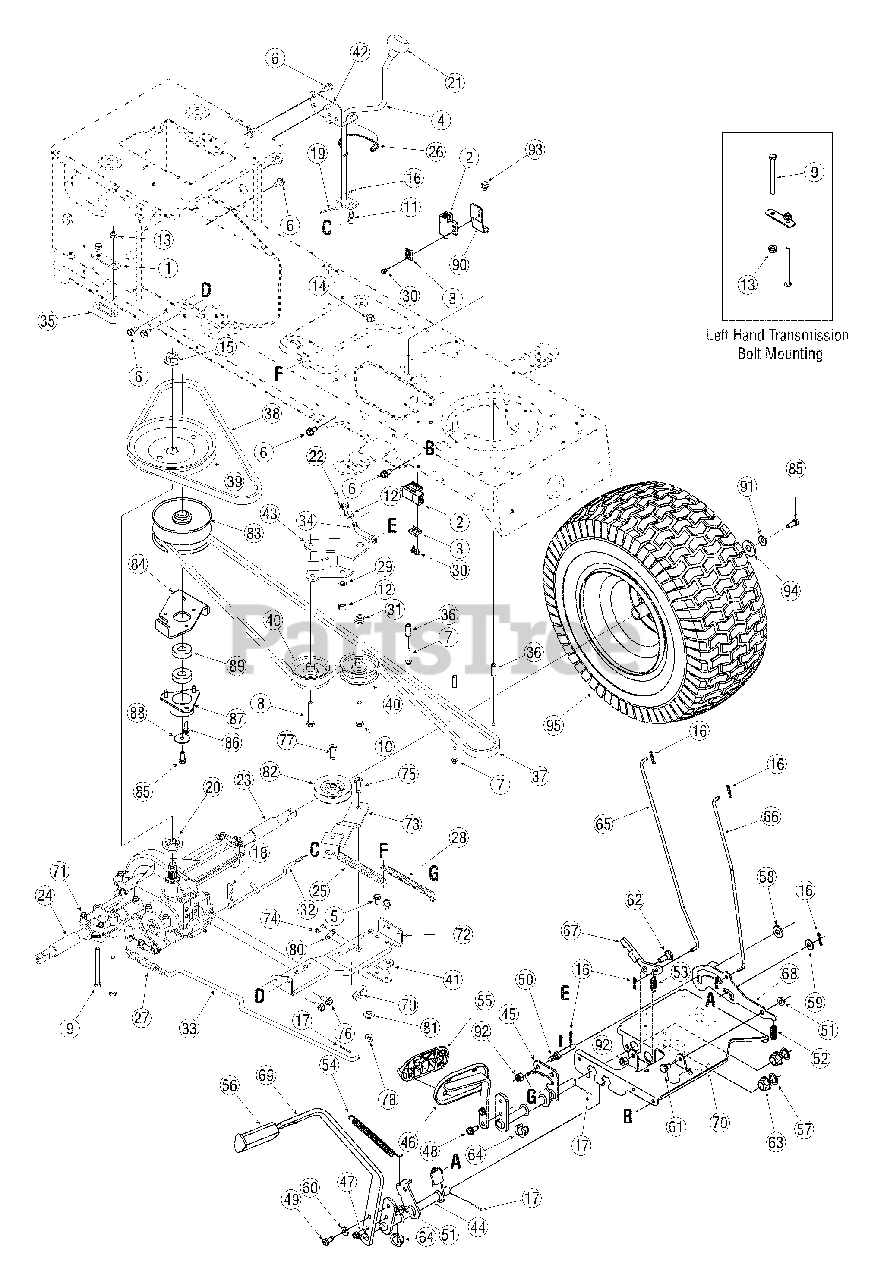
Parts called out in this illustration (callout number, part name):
2	Switch, Interlock
3	Plate, Switch
4	Lever Assembly, Shift
5	Screw, 5/16-18, 0.500
6	Screw, 5/16-12, 0.750
7	Screw, 1/4-20, 1.250
8	Screw, Sems, 3/8-16, 1.500
9	Screw, 5/16-18, 3.50, Gr5
10	Screw, 3/8-16, 2.00, Gr5
11	Adjustment Ferrule 1/4-20 x 1.
12	Nut, Hex, 3/8-24, Gr5
13	Nut, Flange Lock, 5/16-18, Gr F, Nylon
14	Nut, Flange Lock, 3/8-16, Gr F, Nylon
15	Nut, Flange, 9/16-18, Gr2
16	Pin, Cotter,.072 Dia. x 1.13
17	Pin, Cotter, 3/32, 1.0
18	Cotter Pin, Internal,.125 Dia.
19	Pin, Cotter, 1/8 x 1.25
20	Pulley Hub, 5/8 Spline
21	Knob, Shift
22	Ball Joint
23	Sleeve,.758 x.821 x 3.3125
24	Sleeve,.758 x.821 x 2.4375
25	Spring, Extension,.62 Dia x 6.12
26	Spring Clip, Shifter
27	Spring, Extension,.59 OD x 4.00
28	Spring, Extension,.50 Dia x 6.37
29	Washer, Lock, 3/8
30	Screw, #10-16,.50
31	Spacer, Shoulder, 1.00 x.38 x.38
32	Rod, Shift
33	Rod, Brake
34	Idler Rod, Adjustable, 3/8
35	Spacer,.68
36	Spacer,.260 x.372 x 1.030
37	Belt, V-Type
38	Belt, V-Type
39	Pulley, V-Type, 7.25 Dia.
40	Idler Pulley, Flat 2.75 OD
41	Bracket, Shift
42	Bracket, Shift, F-N-R
47	Screw, 5/16-18, 0.875
48	Screw,5/16-18, 0.750
49	Screw, 5/16-18, 0.750
50	Pin, 3/8-16 x 2.68
51	Nut, Flange Lock, 5/16-18, Gr5
52	Spring, Compression,.405 x 1.17
53	Spring, Extension,.50 OD x 1.41
54	Spring, Extension,.50 OD x 6.37
56	Pad, Brake
57	Washer, Flat,.64 x 1.24 x.06, Ht
58	Washer, Flat,.385 x.870 x.092
59	Washer, Flat,.406 x.875 x.059
60	Washer, Flat,.344 x.750 x.120
61	Screw, Shoulder.437 Dia x.162
62	Screw, Shoulder,.50 x.27 Lg, 3/8-16
63	Bearing, Hex Flange
64	Split Bearing, Hex Flange
65	Rod, Brake Lock
66	Rod, Cruise Control
67	Latch, Cruise Control
68	Bracket, Lockout
71	Transmission, Single Speed
72	Bracket Assembly, Torque
73	Bracket, Idler
74	Screw, #8-18 x.50
75	Screw, 3/8-16, 1.00
76	Screw, 5/16-18,.625
77	Screw, 3/8-16, 1.250
78	Nut, Lock, 3/8-16, Nylon
79	Switch Spring, Short
80	Plate, Insulator
81	Spacer, Shoulder
82	Pulley, V-Type, 3.06
83	Pulley Assembly, Variable Speed
84	Bracket, Pulley
85	Screw, 5/16-24,.750
86	Screw, 1/4-20,.750
87	Cup, Bearing
88	Washer, Flat
89	Ball Bearing
92	Nut, Flange Lock, 3/8-16, Gr F, Nylon
93	Screw, 1/4-20 x.500
94	Flat Washer,.350 x 1.59 x.062
